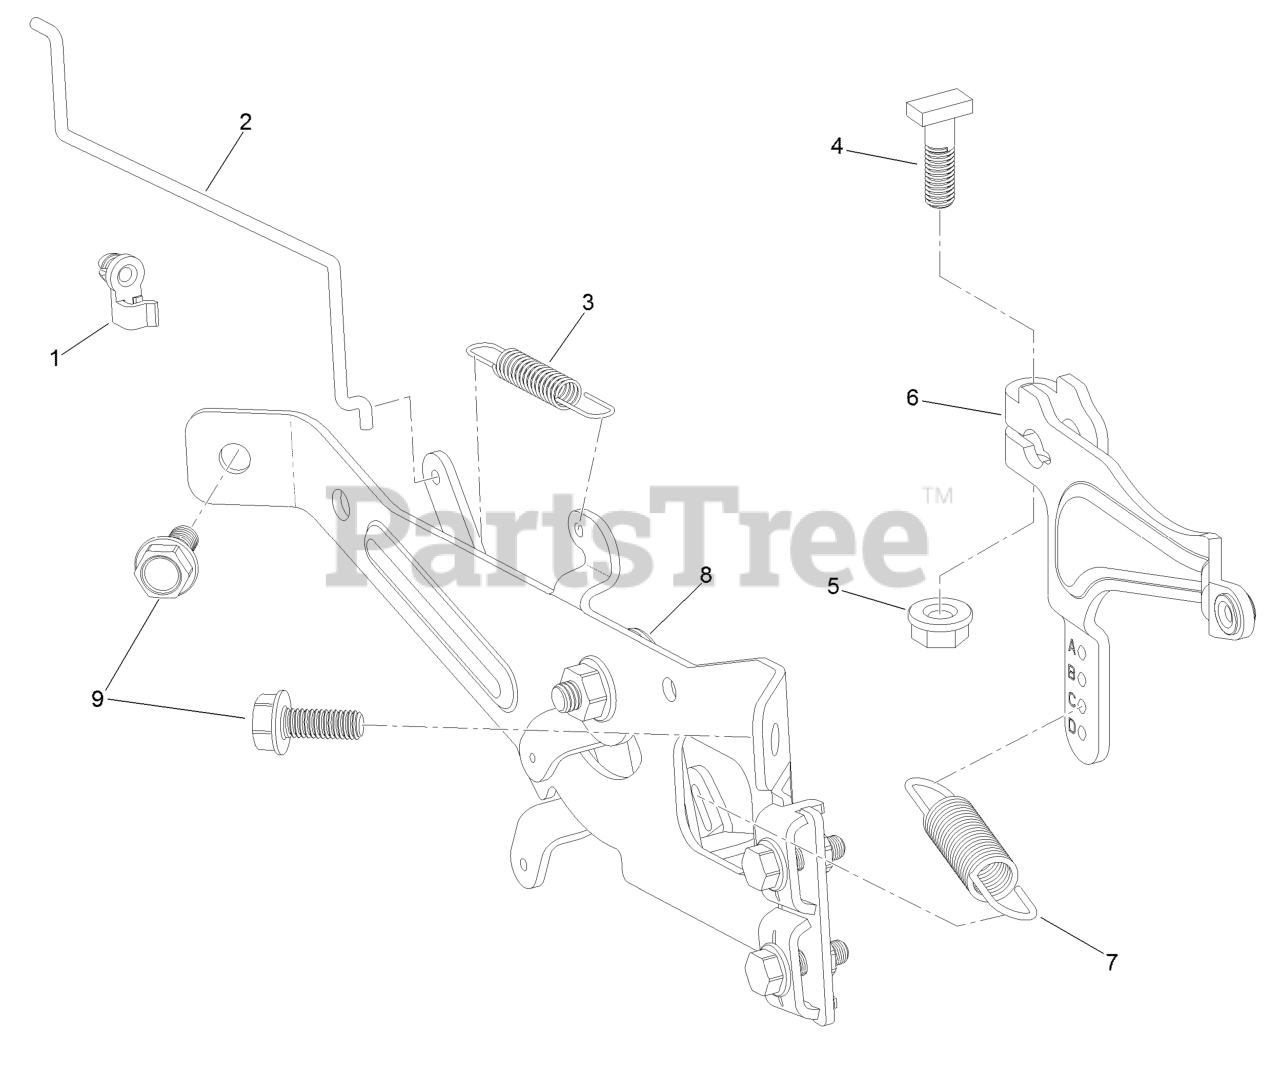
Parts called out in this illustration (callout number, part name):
1	CLIP-LINKAGE
2	LINKAGE-CHOKE
3	SPRING-GOVERNOR
4	BOLT-ARM, GOVERNOR
5	NUT-FLANGE
6	ARM-GOVERNOR
7	SPRING-GOVERNOR
8	PLATE-CONTROL
9	SCREW-HHF
